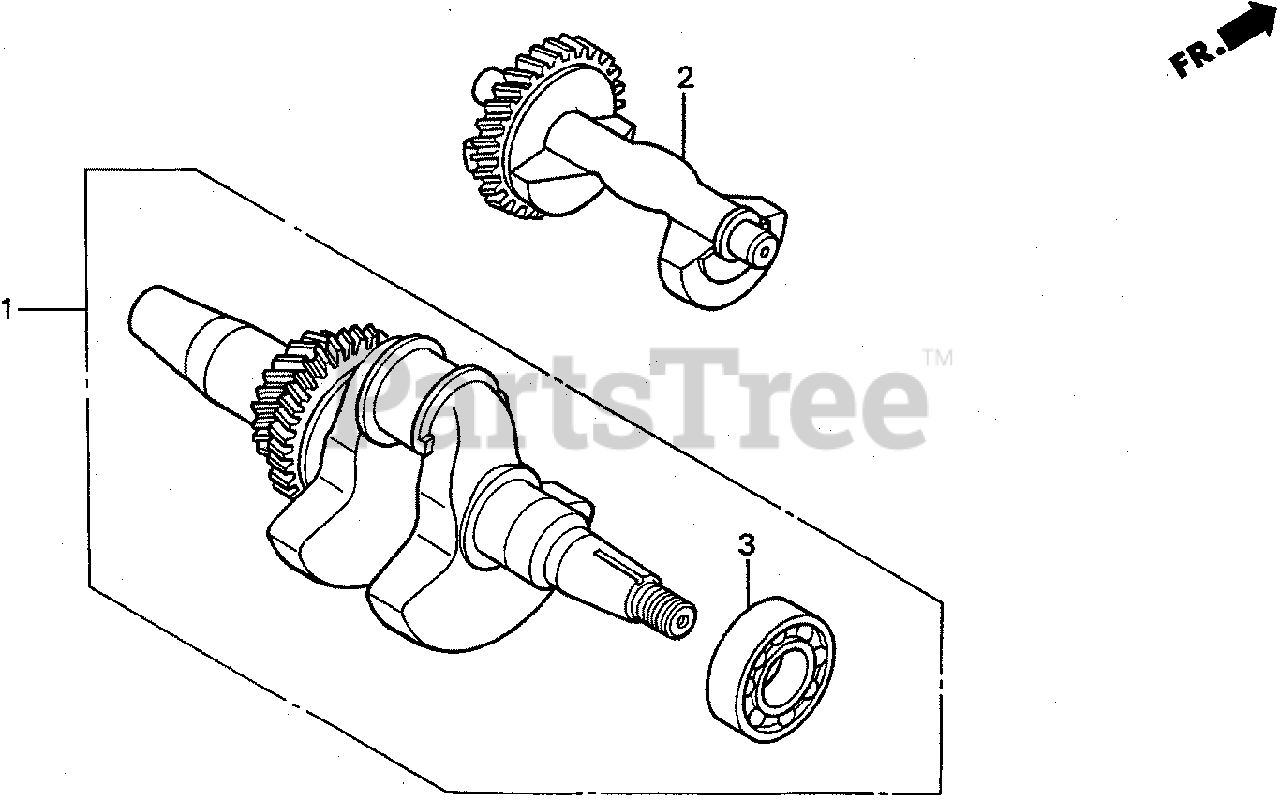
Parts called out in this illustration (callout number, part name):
1	CRANKSHAFT (E-TYPE) (NOT AVAILABLE)
1	CRANKSHAFT (E-TYPE)
1	CRANKSHAFT
2	WEIGHT, BALANCER
3	BEARING, RADIAL BALL (6207)
